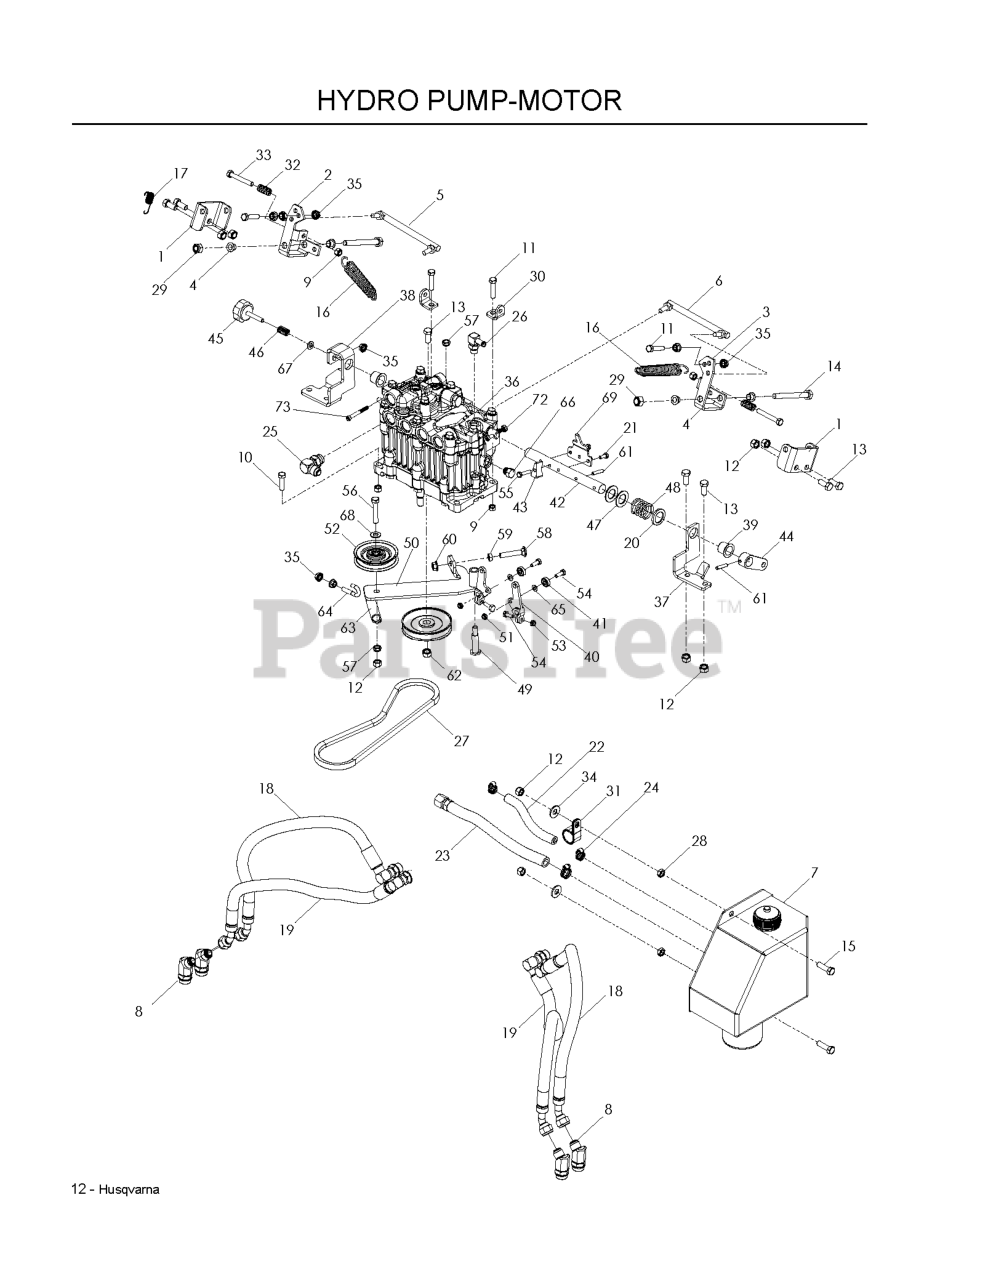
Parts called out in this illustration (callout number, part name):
1	BRACKET - U
2	BELLCRANK LH PAINTED
3	BELLCRANK RH PAINTED
4	BEARING - FLANGE 10MM
5	LINK - CONTROL, RH WB
6	LINK - CONTROL, LH WB
7	RESERVIOR
8	45 DEG STRAIGHT THD ELBOW 8-10
9	NUT 5/16 NYLOC
10	HCS 5/16C X 1 1/4
11	CAPSCREW 5/16 X 1/1/2 HEX HEAD
12	NUT 3/8-16 NYLOC
13	HCS 3/8-16 X 7/8 GR 5 ZD
14	HCS M10-1.58 X 100MM GR8.8 ZD
15	HCS 3/8C X 1 1/4 GR5
16	SPRING-TRANS
20	WASHER, FIBER
21	HCS M6-1.0 X 16MM GR 8.8 ZN
22	HOSE - RETURN
24	HOSE CLAMP T-1865
25	ELBOW, 90 DEGREE
26	FITTING, 90 DEG 9/16-18 X 3/8
27	V-BELT PUMP DRIVE
28	NUT 3/8-16 HEX JAM
29	NUT, M10-1.5 NYLON RING ZD
30	BRACKET, SPRING, BLK
34	WASHER 3/8 FLAT
35	NUT 5/16C WHIZ
36	PUMP, DUP10E
37	SUPT - CAM LH
38	SUPT - CAM, RH PAINTED
39	BEARING - FLANGE, 20MM
40	ARM - HYDRO
41	BEARING - FOLLOWER
42	SHAFT - CAM
43	CAM - TRACKING
44	ARM - SPEED CONTROL
45	ADJUSTMENT KNOB
46	SPRING - COMPRESSION
47	WASHER - 20MM
48	SPRING - COMPRESSION
49	PULLEY, PUMP
51	BOLT, SHOULDER
53	JAM NUT 1/4C (2 2 PW01)
54	HCS 1/4C X 3/4 HCS
55	BOLT - M6-1.0 X 30MM GR 8
56	HCS 3/8C X 2
57	NUT HEX 3/8-16 NYLON, THIN
58	RHSNB 3/8C X 2
59	NUT 3/8-16 HEX JAM
60	NUT 3/8C WHIZ
61	ROLL PIN - 6 MM X 30 MM
62	NUT M10-1.5 L/H HEX
66	PLUG, 6408-6
67	FLAT WASHER 5/16 SAE
68	WASHER 3/8 SAE FLAT
70	NUT M8-1.25 TOP NYL GR10 ZD
71	WASHER.LOCK.HVY.HLCL.SPR.5/16
72	NUT 10-24 NYLOC
73	SCR, #10-24X2 SOCKET HEAD CAP
